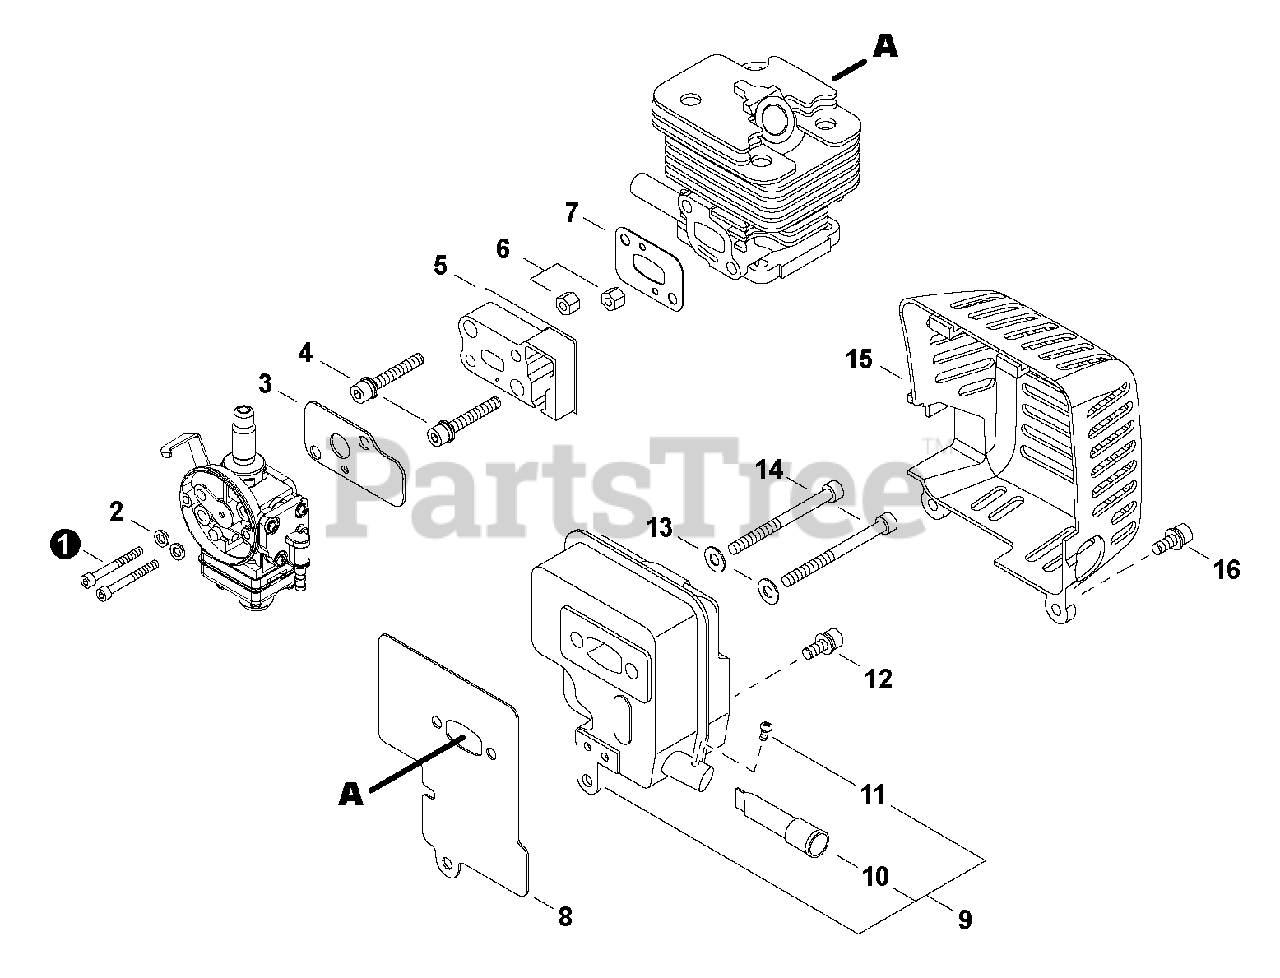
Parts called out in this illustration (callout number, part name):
1	BOLT M5×65
2	WASHER, SPRING 5
3	GASKET, CARBURETOR
4	BOLT 5×20
5	INSULATOR
7	GASKET, INTAKE
8	GASKET, MUFFLER
9	MUFFLER ASSY
10	SCREEN, SPARK ARRESTER
11	SCREW, TAPPING 3×6
12	BOLT 5
13	WASHER, FLAT 5.5×10×0.8
14	BOLT 5×55
15	COVER, MUFFLER
16	BOLT M5×16
